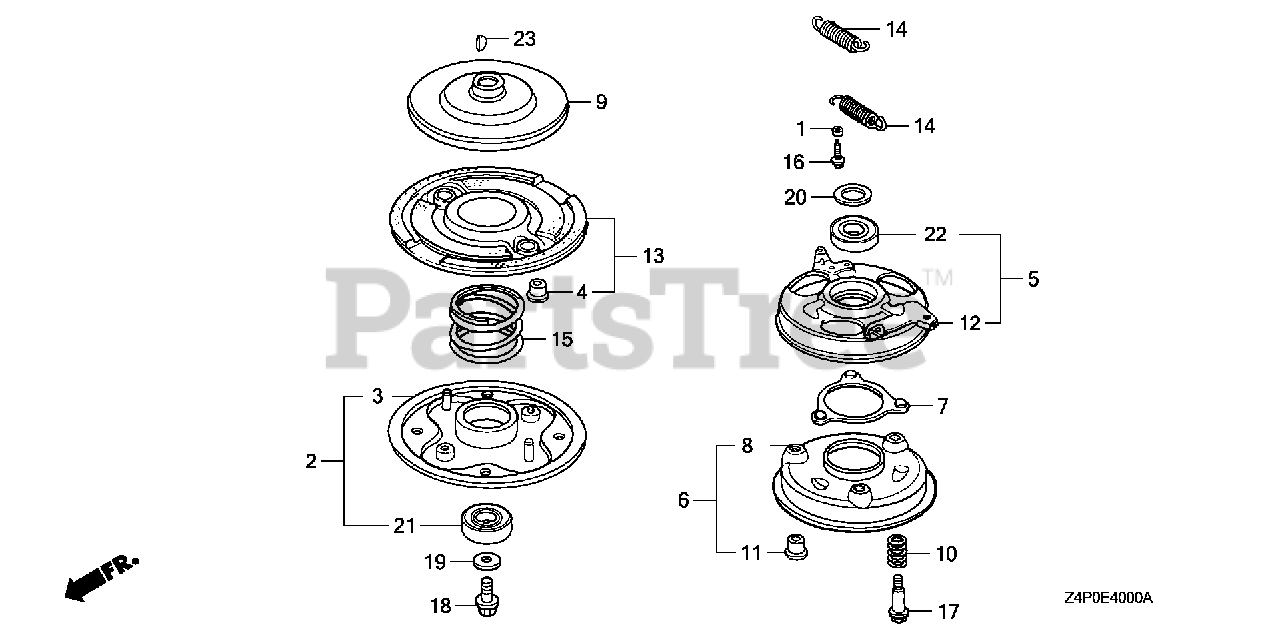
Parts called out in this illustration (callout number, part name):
1	COLLAR, FAN
2	HOLDER ASSY., BLADE
3	HOLDER, BLADE
4	BUSH, BLADE HOLDER
5	PLATE ASSY., BALL CONTROL
6	BRAKE
7	RETAINER, BALL
8	DISK, BRAKE
9	DISK, DRIVE
10	SPRING, BRAKE HOLDER
11	BUSH, BRAKE HOLDER
12	PLATE, BALL CONTROL
13	DISK, DRIVEN
14	SPRING, CLUTCH RETURN (53.0MM)
15	SPRING, CLUTCH (36.6MM)
16	BOLT, FLANGE (6X14) (CT200)
17	BOLT, SPECIAL (6MM)
18	BOLT, HEX. (10X25)
19	WASHER (10MM)
20	WASHER, THRUST
21	BEARING, RADIAL BALL (6204)
22	BEARING, RADIAL BALL (60/22)
23	KEY, WOODRUFF (16X15)
